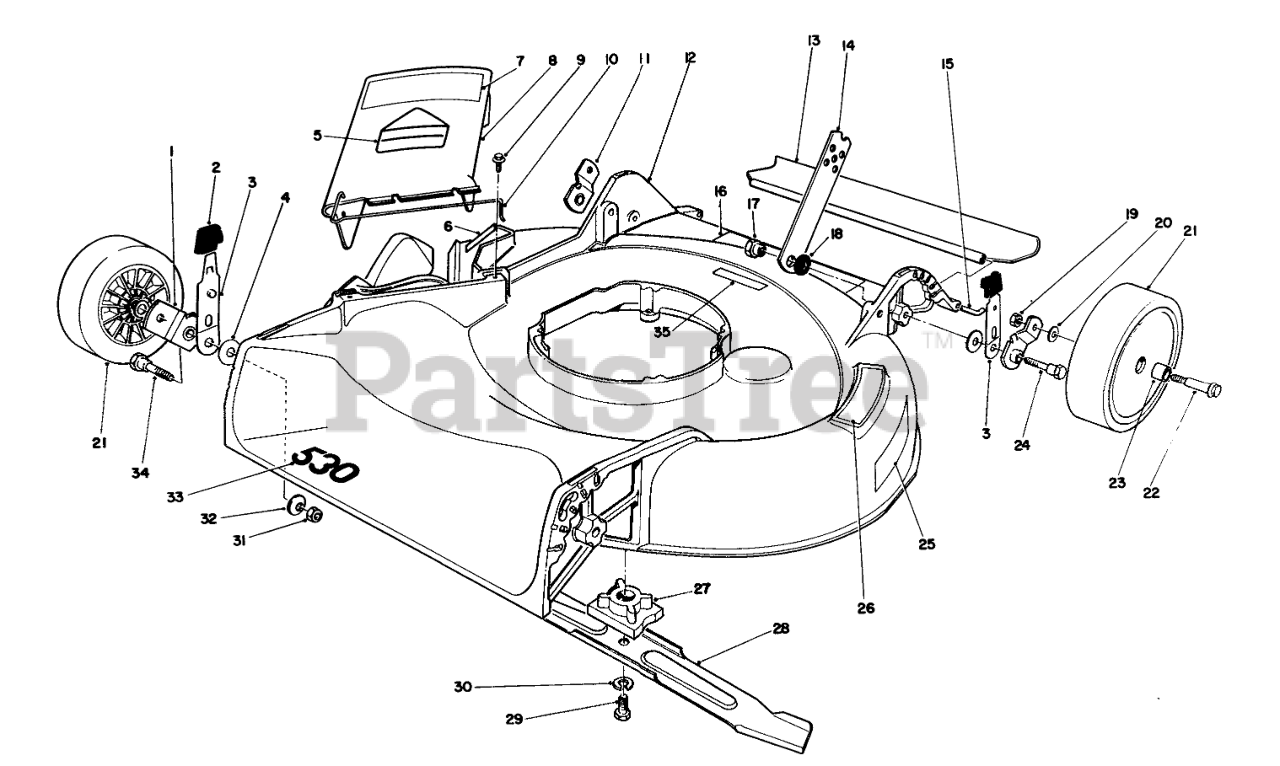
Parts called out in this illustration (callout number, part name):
1	Pivot Arm
2	KNOB-ARM
3	SPRING ARM ASM
4	WASHER-PIVOT
5	DECAL-DANGER
6	Decal-Danger
7	Decal-Danger(French)
8	Deflector Assembly (Incl. Ref. #5, 7 & 10)
9	SCREW-HWH
10	SPRING HINGE
11	Pivot Arm
12	HOUSING/DECAL
13	REAR SAFETY SHIELD 21
14	HANDLE LATCH
15	SHIELD ROD
16	Danger-Decal
17	HANDLE PIVOT NUT
18	SPACER
19	Nut
20	WASHER
21	Wheel & Tire Assembly (Incl. Ref. #23)
22	BOLT-WHEEL
23	BUSHING
24	PIVOT SCREW
25	Decal-Step
26	STEP PAD DECAL
27	BLADE RETAINER
28	Blade
29	SCREW-HH
30	WASHER-LOCK
31	NUT-LOCK, NI
32	WASHER-BELLEVILLE
33	Decal-530
34	5/16-18 PIVOT SCREW
35	Decal
